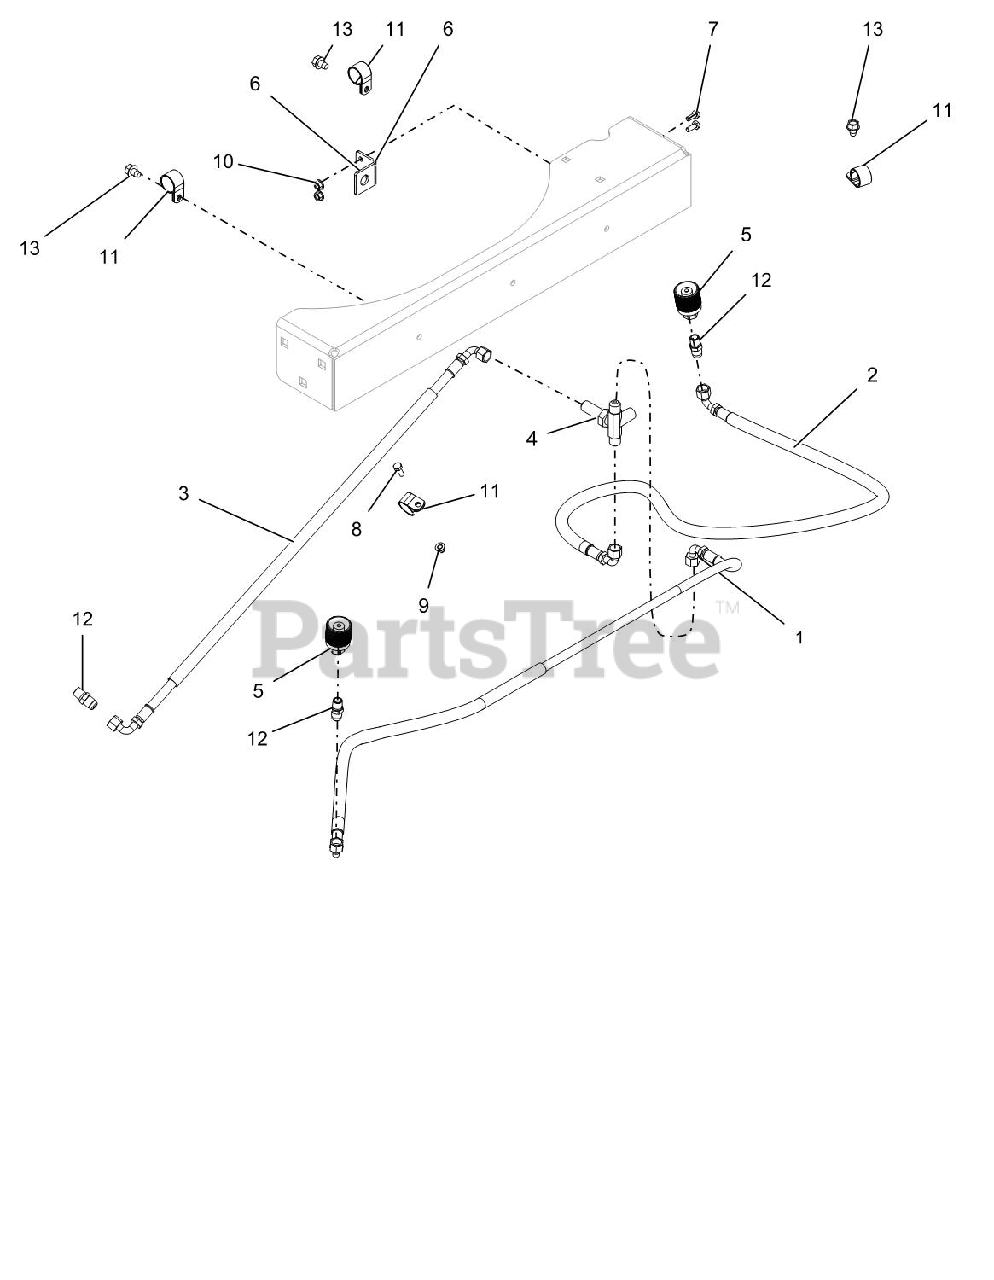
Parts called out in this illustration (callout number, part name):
1	HOSE,LPG SS25UL-6-4-6-47.25
2	HOSE,LPG SS25UL 6-4-6-45.00"
3	HOSE, LPG SS25UL 6-6-6-30.50
4	VALVE,SHERWOOD T PV3866 LPG
5	FTG, LPG TANK COUPLER LH THRD
6	MOUNT, TEE VALVE
7	BLT-HEX .25-20X.63 GR5 YWZC
8	BLT-HEX .25-20X.75 GR5 YWZC
9	NUT-LK-NYL-FLG .25-20 YWZC
10	NUT-LK-TOP-FLG .25-20 YWZC
11	CLAMP, COUSHIONED STEEL REV
12	FTG,ADP 1/4MNPT X 5/8MJIC
13	SCR-TAP .38-16X.50 HWH TR YWZ
